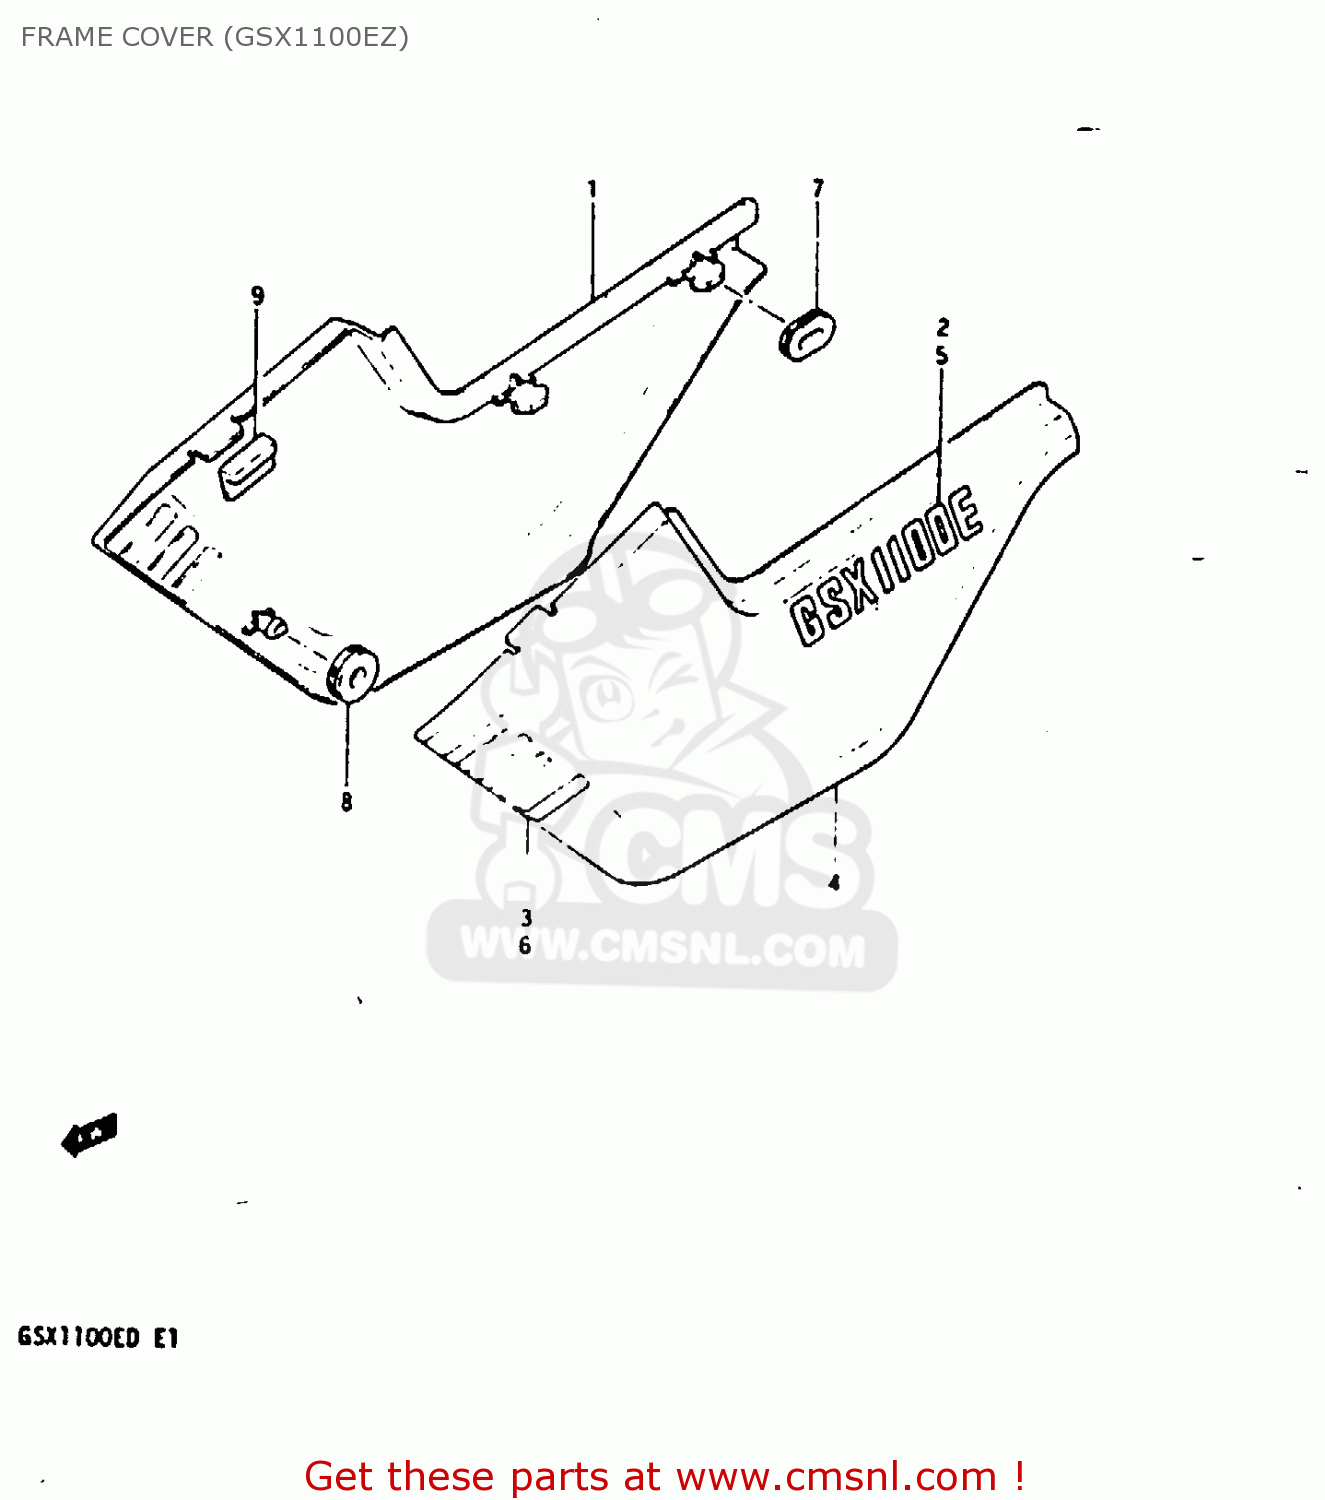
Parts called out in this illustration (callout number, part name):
1	COVER, FRAME RH (GOLD)
2	EMBLEM, LH
3	LABEL, DENT
4	COVER, FRAME LH (GOLD)
5	EMBLEM, LH
6	EMBLEM,FRAME COVER,CENTER
7	CUSHION
8	CUSHION
9	CUSHION,FRAME COVER
